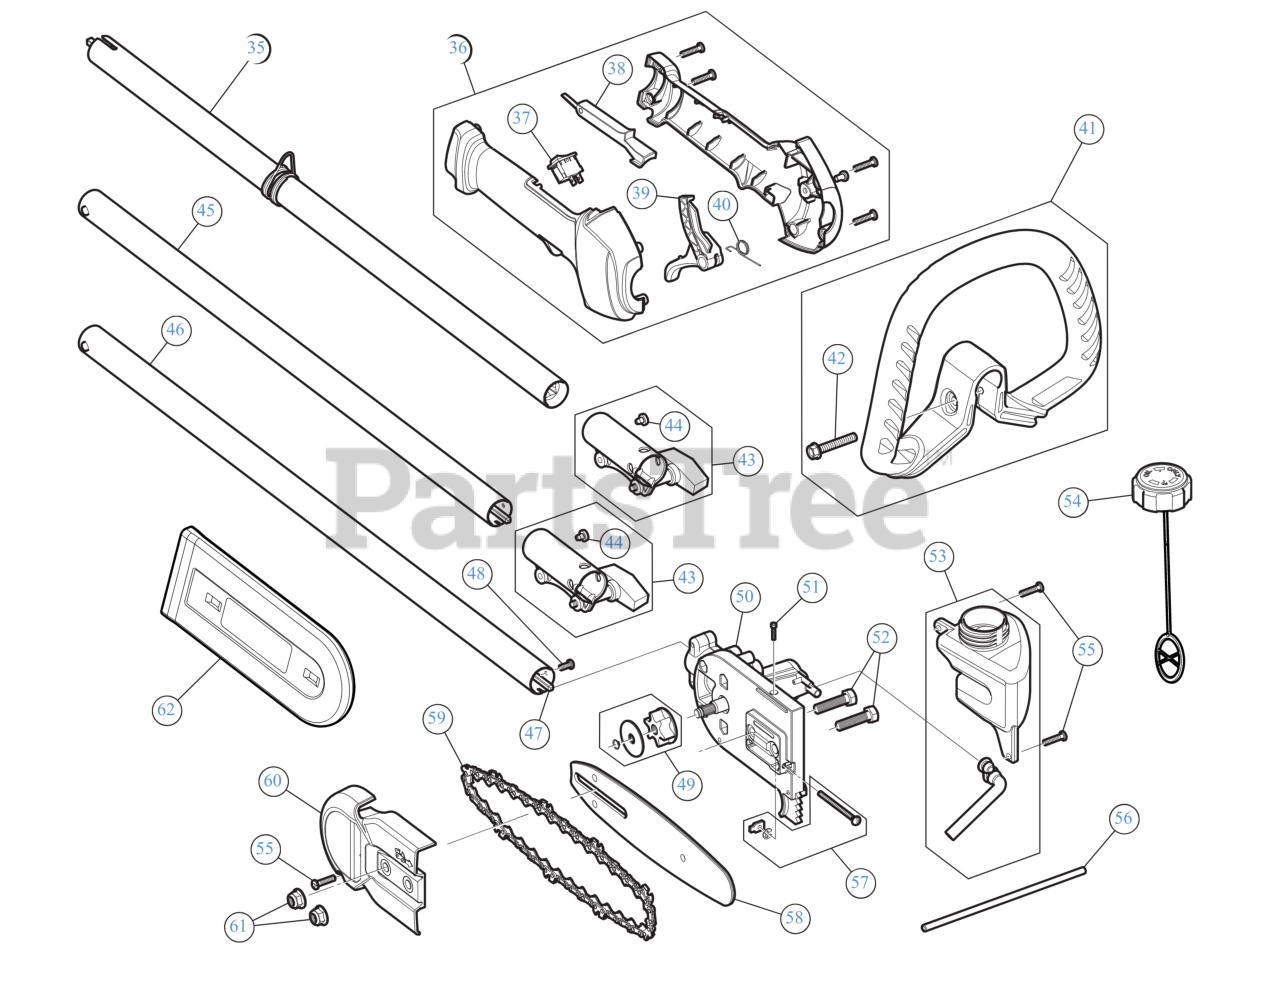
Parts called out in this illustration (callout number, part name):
35	BOOM ASSEMBLY UPR
36	THROTTLE GRIP ASSEMBLY
37	SW, MOMENTARY ON/O
38	LEVER LOCK OUT
39	THROTTLE TRIGGER
40	TRIGGER SPRING
41	HANDLE ASSEMBLY
42	BOLT 1/4-20X1 1/2
43	SPLIT BOOM COUPLER KIT
44	SCREW, 10-32X.250 TA
45	HOUSING ASSEMBLY UPPER W/FLEXSHAFT
46	LOWER DRIVE SHAFT HOUSING
47	FLEXIBLE DRIVE SHAFT
48	SCREW 1/4-20 X.500
49	SPROCKET ASSEMBLY
50	GEAR BOX ASSEMBLY
51	SCREW 4X40X.50
52	SCREW 5/16-18 x 1.25 GR5
53	OIL TANK ASSEMBLY
54	FUEL CAP ASSEMBLY
55	SCREW, #8-16X.750 PH
56	OIL LINE
57	CHAIN TENSION HDW
58	BAR 8" SPROCKET NOSE
59	CHAIN 8" 34 LINK .043 GAUGE
60	CHAIN GUARD
61	FLANGE LOCK NUT 5/16-18
62	8" SCABBARD
